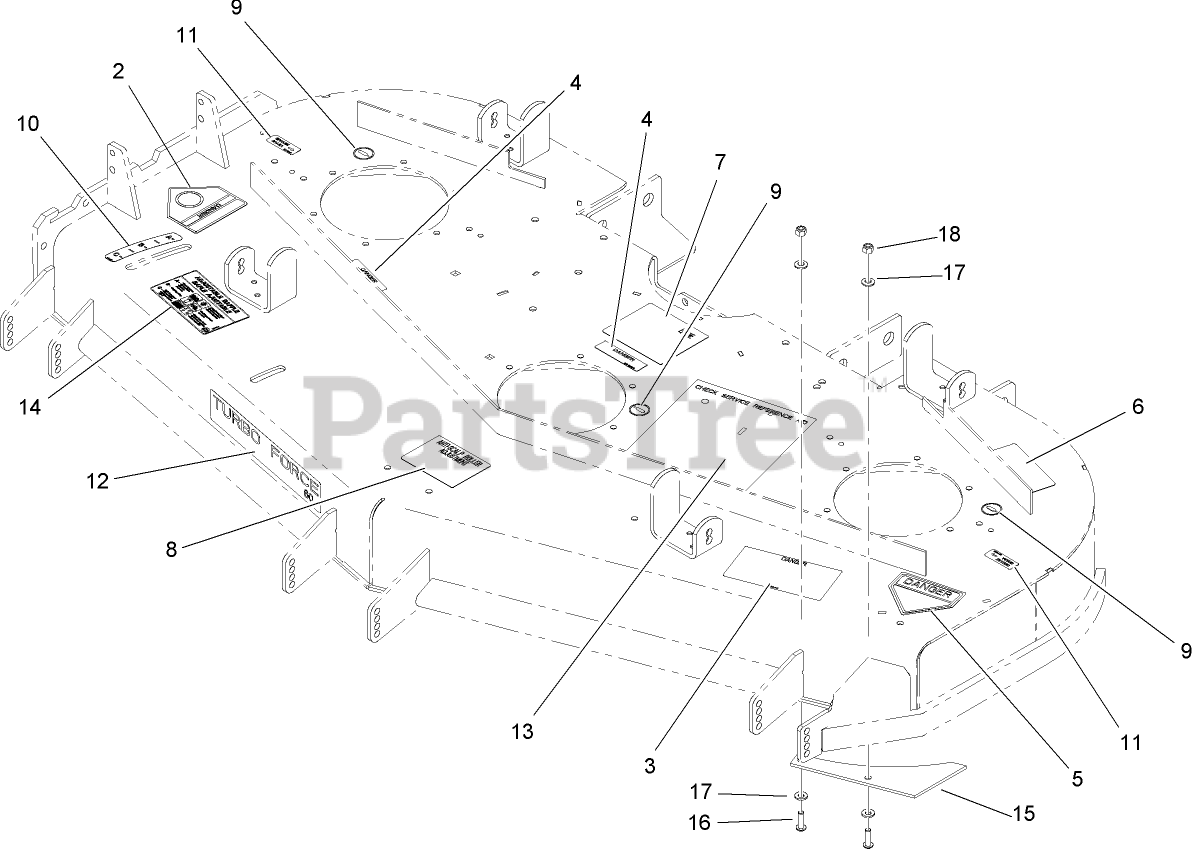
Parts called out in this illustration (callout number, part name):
2	DECAL-DANGER
3	DECAL-DANGER, THROWN OBJECT
4	DECAL-COVER, MISSING
5	DECAL-DANGER
6	DECAL-TORQUE
7	Decal-Routing, Belt
8	DECAL-SCALP, ANTI
9	DECAL-GREASE
10	DECAL-SETTING, BAFFLE
11	Decal-Grease
13	Decal-Service, Check
14	DECAL-ADJUSTMENT, BAFFLE
15	PLATE-TURBO
16	SCREW-HSBH
17	WASHER-SPRING
18	NUT-LOCK, NI
